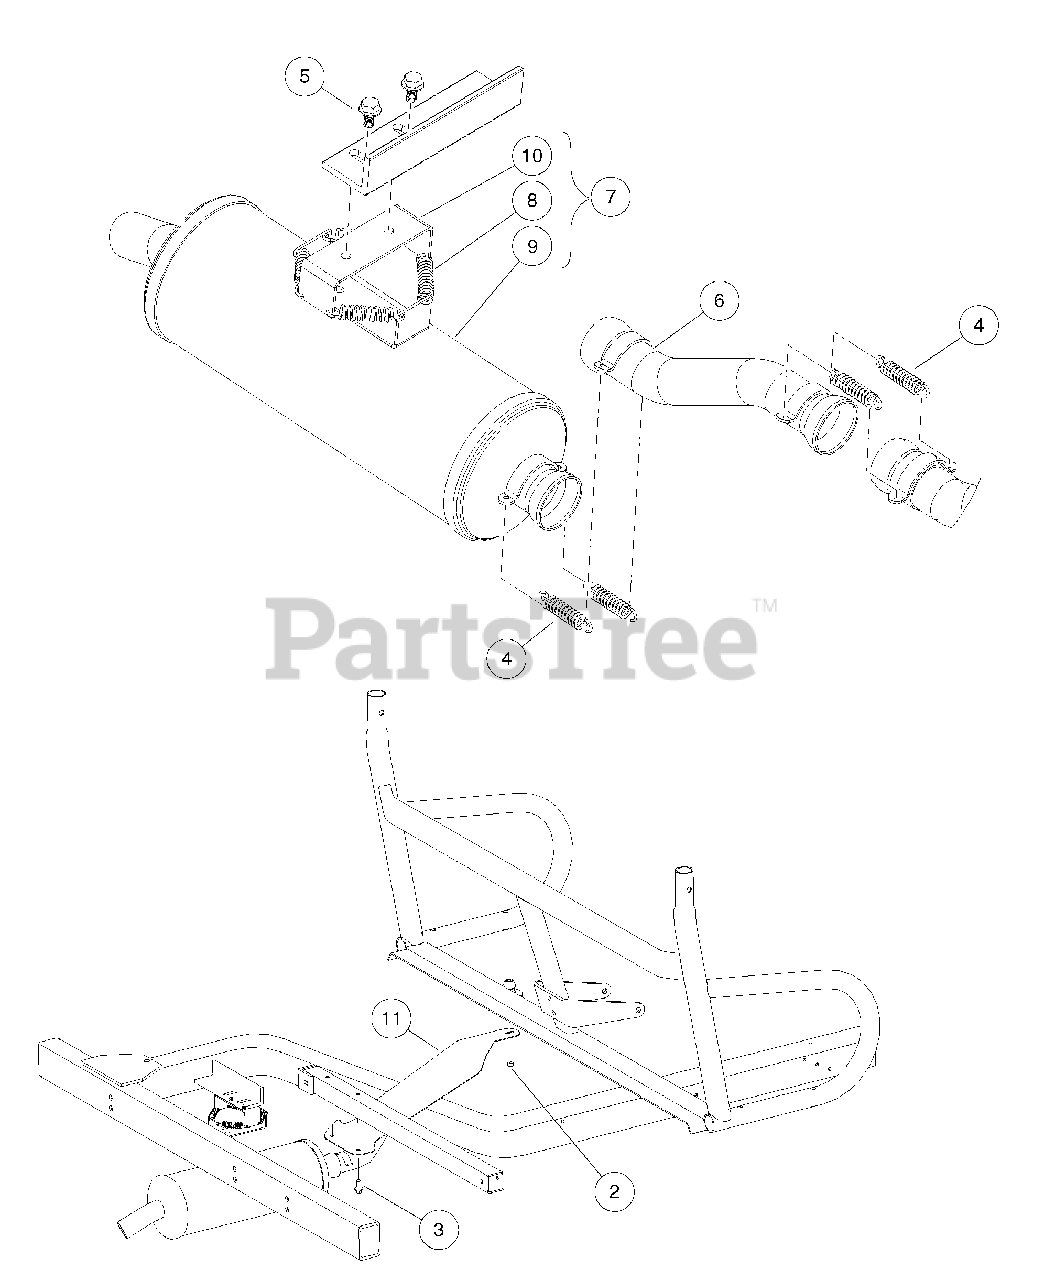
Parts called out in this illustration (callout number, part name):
1	Instl, Exhaust, AWD
2	Locknut, M6-1.00 Nylon Insert
3	M8-1.25x20 Taptite
4	Spring, Exhaust
5	Bolt Flanged Head, M8 X1.25x 16 with Loctite
6	Pipe, Exhaust, Int, Offset
7	Asm, Muffler, AWD Homologation
8	Spring, Exhaust
9	Muffler
10	Bracket, Muffler
11	Shield, Exhaust, Clearance
